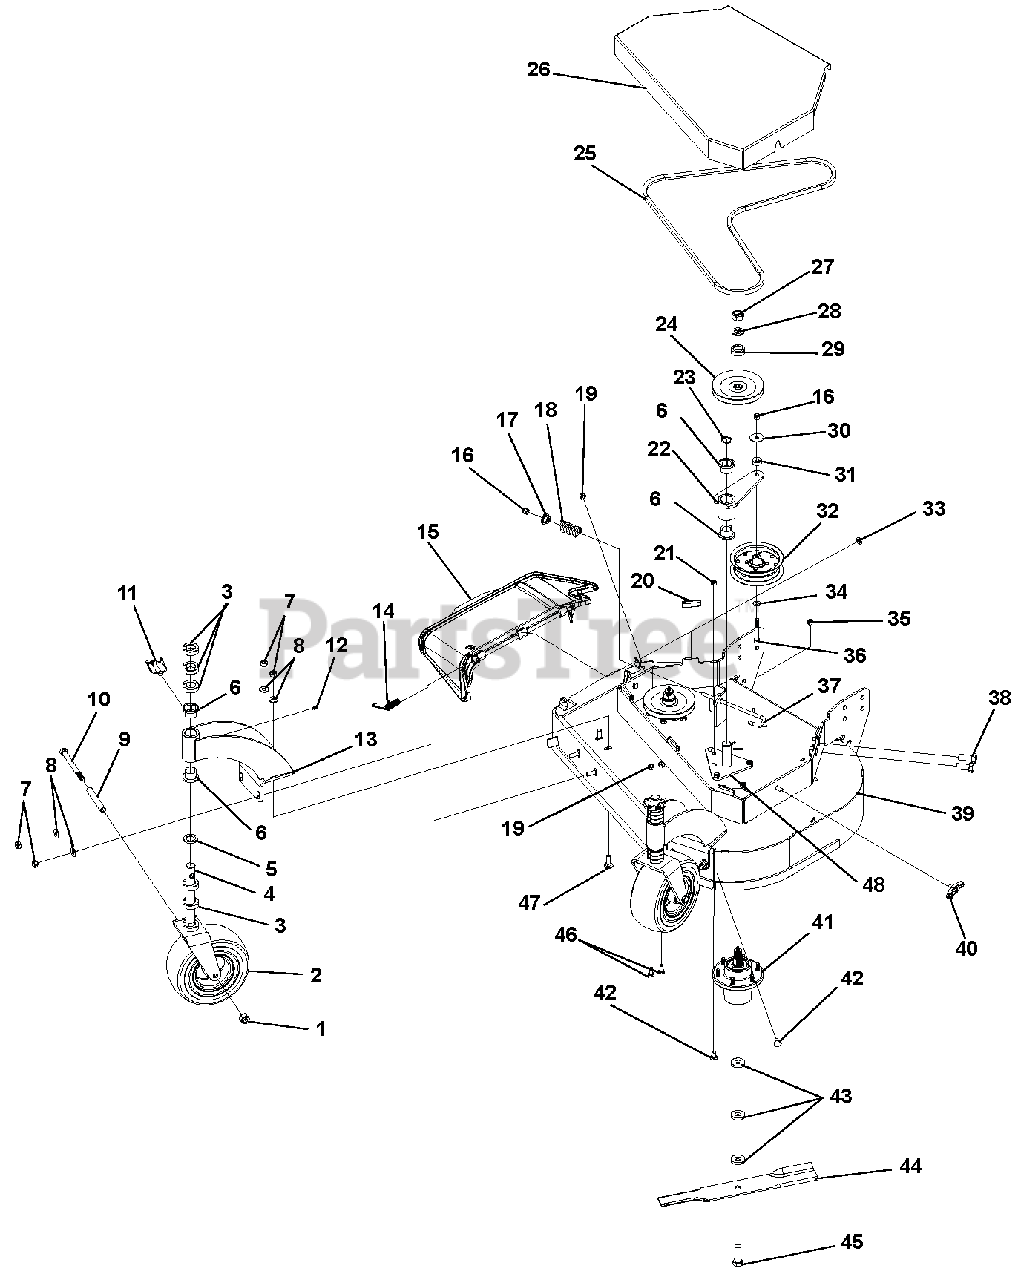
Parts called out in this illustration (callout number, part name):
1	LOCKNUT, 1/2-13 NYLOC Y
2	ASSY, WHEEL AND TIRE 9X3.5
3	C-SPACER, 1.00 X 1.77 X .500
4	WLDT, CASTER YOKE W/EVRRD PNT
5	BUSHING, 1.03 X 1.50 X .179 Y
6	BRG, FLG 1.00X1.25X1.00
7	LOCKNUT, 7/16-14 CROWN Y
8	WASHER, .375 REG FLAT Y
9	TUBE, CASTER AXLE
10	BOLT, 1/2-13X5.50 HEX 5 Y
11	PIN, KLIK .438X2.00
12	FTG, 1/4-28 STRGT GREASE ZERK
13	WLDT, CASTER SUPP EVR PAINT
14	SPRING, TORSION .460"X.138"
15	CHUTE DISCHARGE ASSY #
16	LOCKNUT, 3/8-16 NYLOC Y
17	KEEPER, SPRING
18	SPRING, COM 1.22X.162X2.50 Y
19	LOCKNUT, 3/8-16 CROWN Y
20	TRIM, LOCK 1/4" EDGE
21	@NUT-LK-CTR-JAM .375-16 YWZC
22	WMT, IDLER ARM
23	SNAP RING, 1.00 X .042 EXT
24	PULLEY, NARROW SPLINE
25	BELT, HB 80.3 EL AMD OHR
26	SHIELD, BELT 32/36 GEAR WASP
27	LOCKNUT, 3/4-16 CROWN PL
28	WASHER, .75X1.3125X.120
29	SPACER, SPINDLE TOP-PULLEY
30	WASHER, .375X1.50X.063 FLAT Y
31	BUSHING, .380 X 1.00 X .410 Y
32	PULLEY, FLAT 5.00X.375 W/BRG
33	RETAINER #
34	WASHER, .406X.813X.065 FLAT Y
35	NUT, 3/8-16 STD HEX GR5 Y
36	BOLT, 3/8-16X2.75 HEX 5 Y
37	J-BOLT, 3/8-16 X 7.88 Y
38	BOLT, HEX 5/8-11 1.5" GR8 YWZC
39	36" WASP GEAR DECK W/DECALS
40	KNOB, 3/8-16 INSERT
41	ASSY, SPINDLE S/O
42	BOLT, 3/8-16X.750 CRG 5 LN Y
43	WASHER, .630X1.50X.250 FLAT Y
44	BLADE, 18.000 X .80 LIFT
45	BOLT, 5/8-11 X 2.00 HEX 8 Y
46	BOLT, 3/8-16X.750 HEX 5 Y
47	BOLT, 7/16-14X1.25 CRG 5 Y
48	WLDT, IDLER PIVOT MOUNT
